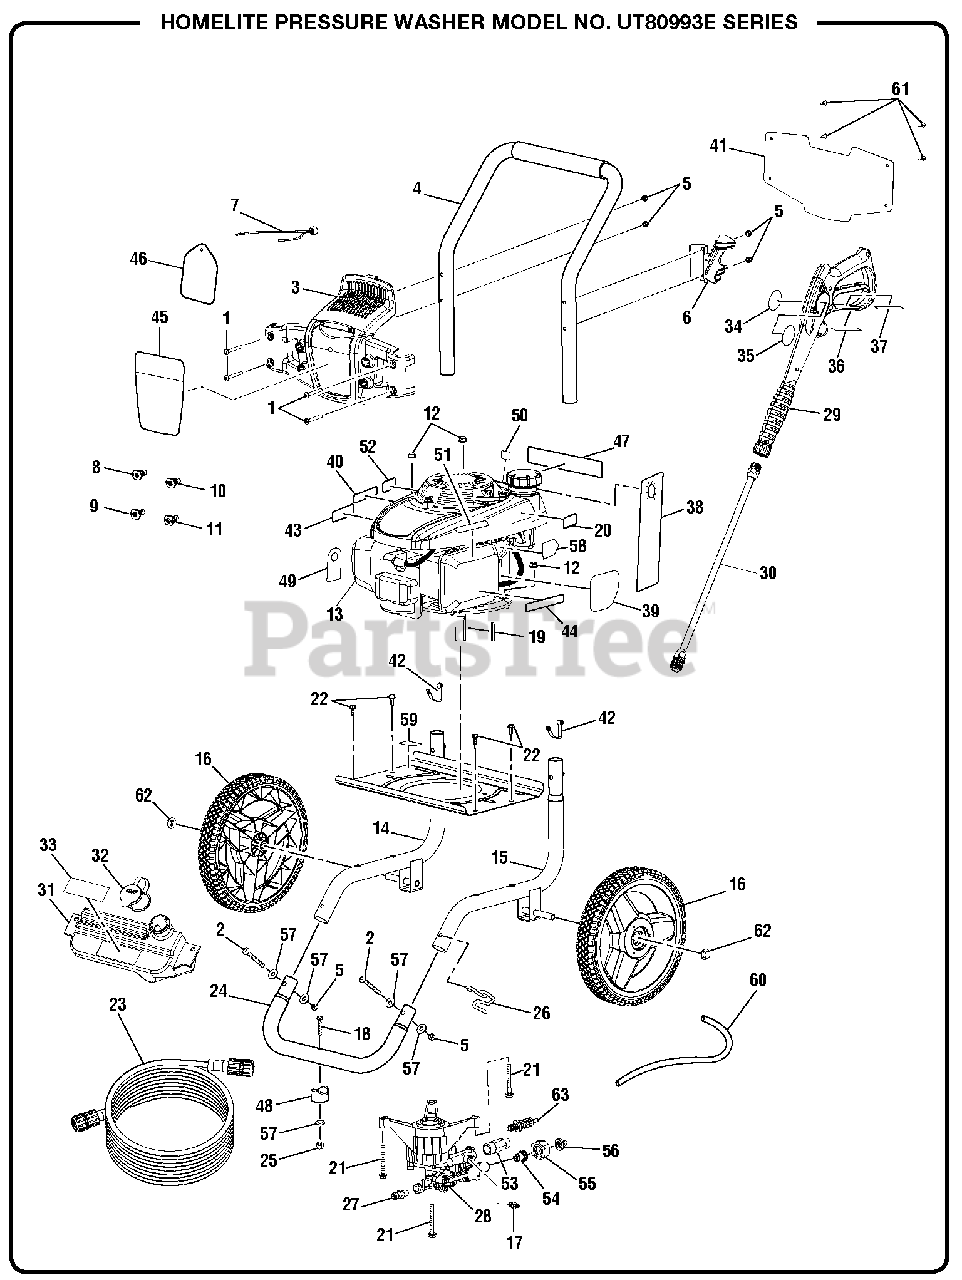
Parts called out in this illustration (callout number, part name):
1	Screw (M6 x 48 mm, T30 Torx Hd.)
2	Bolt (M6 x 55 mm)
3	Hose and Nozzle Holder Assembly
4	Handle w/Foam
5	Lock Nut (M6)
6	Wand Holder
7	Bungee Cord Assembly
8	40deg Nozzle
9	Soap Nozzle
10	25deg Nozzle
11	0deg Nozzle
12	Flange Nut (M8 x 1.25)
13	Engine (Honda GCV 160, 160cc OHC Vertical)
14	Main Frame Assembly A
15	Main Frame Assembly B
17	Detergent Suction Kit
18	Screw (1/4-20 x 1.85 in., T30 Torx Hd.)
19	Output Shaft Key (40 mm)
20	Do Not Mix Label
21	Bolt (M8 x 60 mm, Flange Hd.)
22	Bolt (M6 x 16 mm)
23	Hose (25 ft., 3100 psi)
24	Front Frame
25	Lock Nut (1/4-20)
26	Wand Holder Loop
27	Thermal Release Valve
28	Pump
29	Trigger Handle Assembly
30	Extension Wand
31	Soap Tank
32	Soap Tank Cap
33	Soap Dilution Label
34	Label (Wand Logo)
35	Label (Wand Warning)
36	Warning Label (Fr/Sp)
37	Label (Wand Rating)
38	Danger Hangtag
39	Engine Control Label
40	Combustion Label
41	Quick Start Panel
42	Lock Button w/Spring Clip
43	Hot Surface Label
44	EMC Label
45	Performance Label
46	Nozzle Hangtag
47	Danger Label
49	Dipstick Hangtag
50	No E85 Label
51	Inquiries Label
52	Lubricant Label
53	Outlet Tube
56	Filter Screen (Pump Inlet)
57	Washer (1/4 in.)
58	Engine On/Off Label
59	Oil Fill Location Label
60	Chemical Siphon Tube
61	Screw (#6-20)
62	Push Cap Nut (1/2 in.)
63	Unloader Valve
